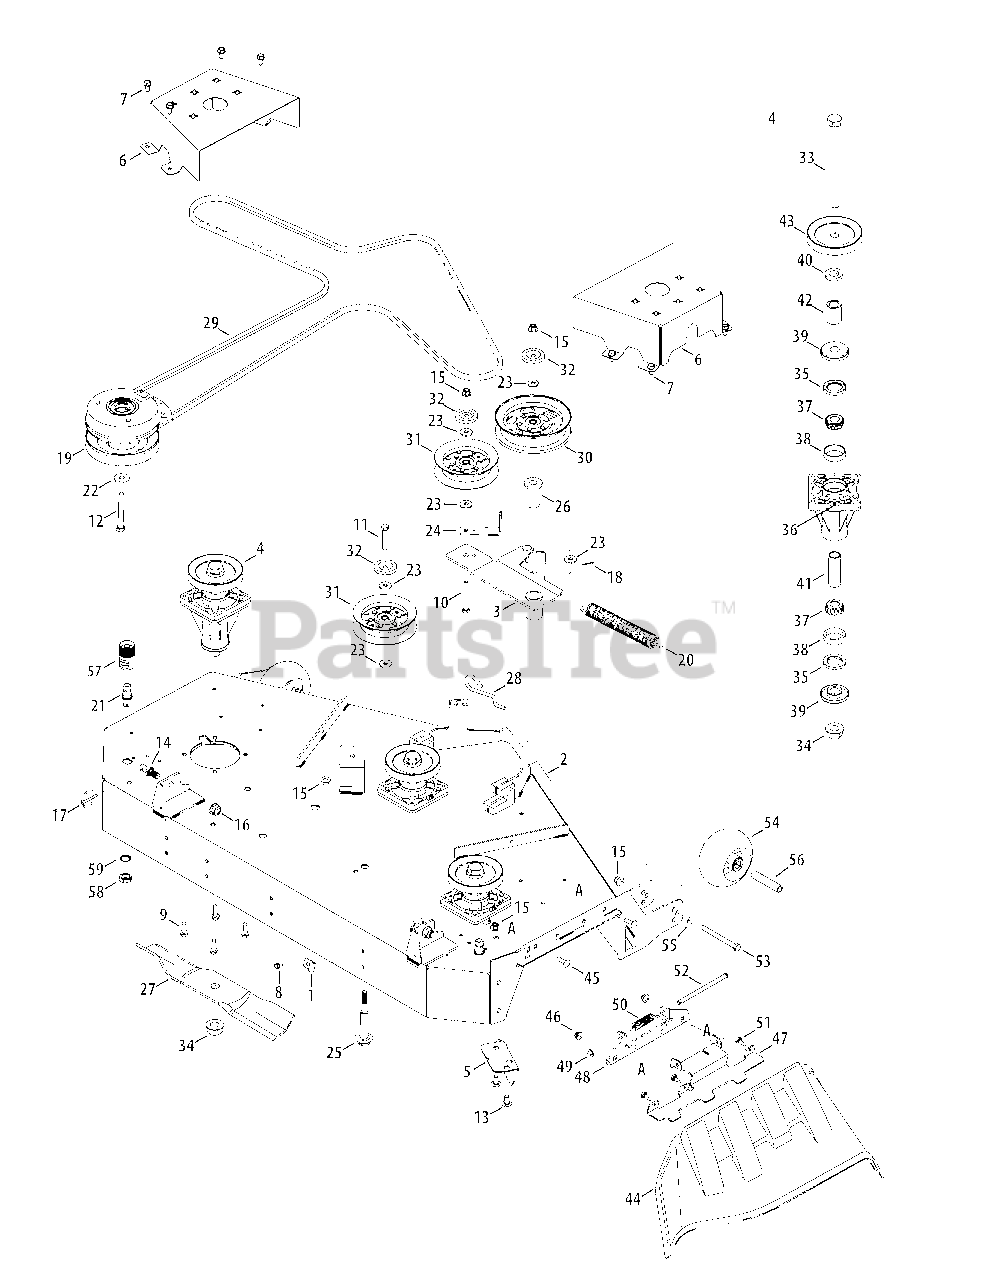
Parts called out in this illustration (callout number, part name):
1	Bracket, Hook Retainer
2	48" Deck
3	Deck Idler Assembly
4	Spindle Assembly
6	Belt Cover
7	Hex Washer Screw, 5/16-18 x .750
8	Hex Washer Screw, 1/4-20 x .500
9	Hex Washer Screw, 5/16-18 x 1.250
10	Hex Cap Screw, 3/8-16 x 2.50
11	Hex Cap Screw, 3/8-16 x 2.00
12	Screw, 7/16-20 x 3.25
13	Carriage Screw, 3/8-16 x .75
14	Pin, Shoulder Lock, .500
15	Flange Lock Nut, 3/8-16
16	Flange Lock Nut, 1/2-13
17	Pin, Lynch x .1875
18	Cotter Pin 3/32" Dia. x .75 Lg.
19	Electric PTO Clutch
20	Extension Spring, 1.25 OD x 1.751
21	Deck Water Nozzle
22	Flat Washer, .450 x 1.25 x .164
23	Flat Washer, .406 x .875 x .105
24	Belt Guard Bracket
25	Shoulder Boult, .625 x 2.12, 3/8-16
26	Shoulder Spacer, 1.055 x .627 x 2.292
27	Blade, 17.00
28	Deck Spring Rod
29	V-Belt
30	Idler Pulley, 5.00 Dia.
31	Idler Pulley, 4.00 Dia
32	Pulley Cap
33	Hex Cap Screw, 3/4-16 x 8.25
34	Nut, 3/4-16, Flangelock
36	Grease Fitting
37	Cone Bearing
38	Cup Bearing
39	Spindle Spacer
40	Spacer, .812 ID x .218 LG
41	Spacer, .78 x 1.00 x 2.895
42	Spacer, .792 x 1.20 x 1.628
43	V-Type Pulley
44	Discharge Chute Assembly
45	Carriage Bolt, 5/16-18 x 1.00
46	Flange Lock Nut, 5/16-18
49	Push Cap
50	Torsion Spring
51	Shoulder Screw, 1/4-20
52	Chute Rod
53	Hex Cap Screw, 3/8-16 x 4.0
54	Deck Ball Wheel, 5.0
55	Flat Washer, .406 x .875 x .059
56	Wheel Spacer
57	Water Nozzle Adapter
58	Hex Nut, M-16 x 1.5
59	Lock Washer, 17 x 23.8 x 1.95
